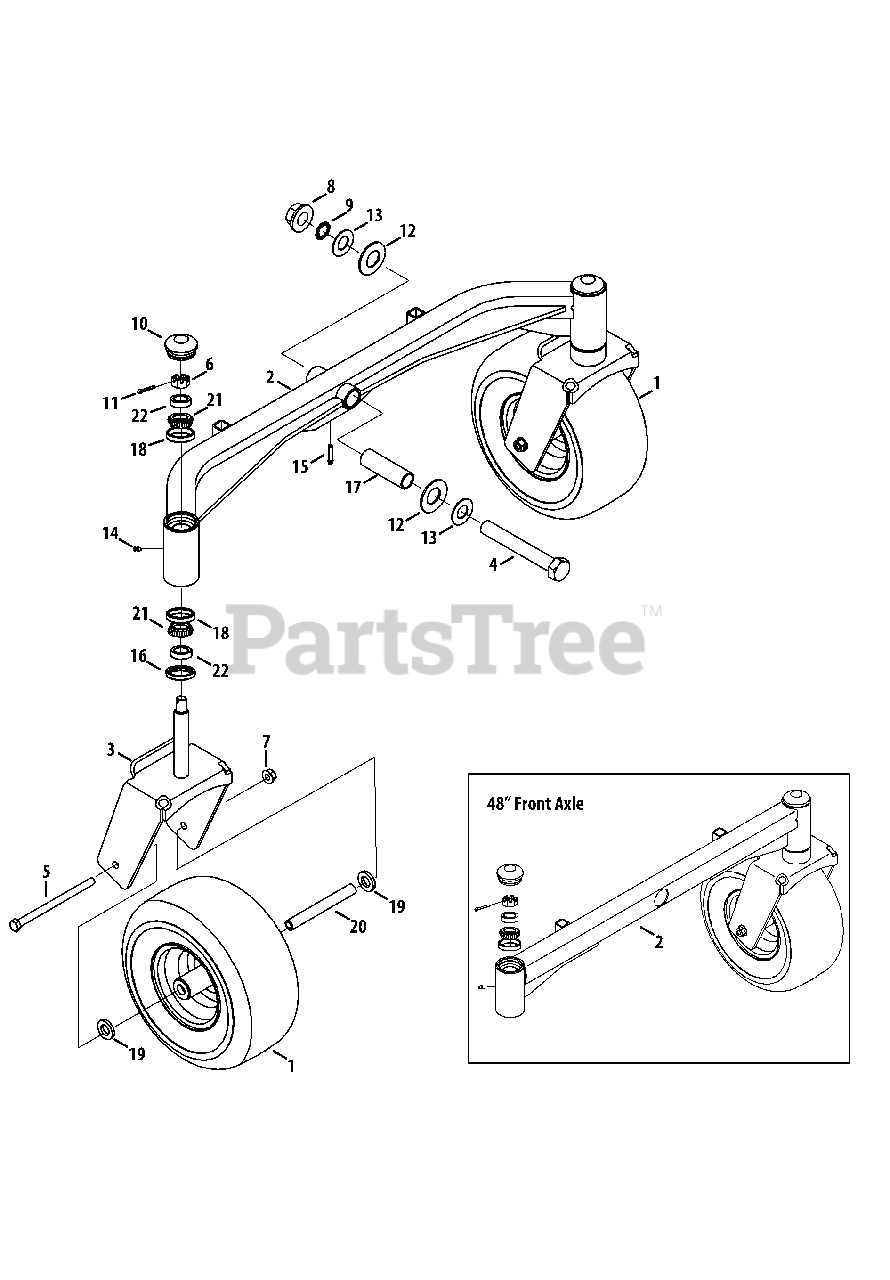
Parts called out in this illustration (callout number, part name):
1	Wheel Assembly, 13 x 6.50-6
2	Front Axle (54" & 60")
3	Yoke, Caster Wheel
4	Hex Cap Screw, 1-14 x 7.0
5	Hex Cap Screw, 1/2-13 x 7.75
6	Nut, 3/4-16, Slotted
7	Nut, 1/2-13, Flangelock
8	Nut, 1.0-14, Flangelock
9	Retainer Ring
10	Axle Grease Cap
11	Cotter Pin, 5/32 x 1.25
12	Bell Washer, 1.25 x 2.50 x .180
13	Washer, 1.00 x 2.00 x .075
14	Grease Fitting, 1/4-28
15	Grease Fitting, 1 39/64
17	Spacer, 1.005 x 1.247 x 4.1
18	Cup Bearing
19	Spacer, .812 ID x .218 LG
20	Spacer, .515 x .749 x 6.313
21	Cone Bearing
22	Spacer, 1.00 x 1.50 x .437
